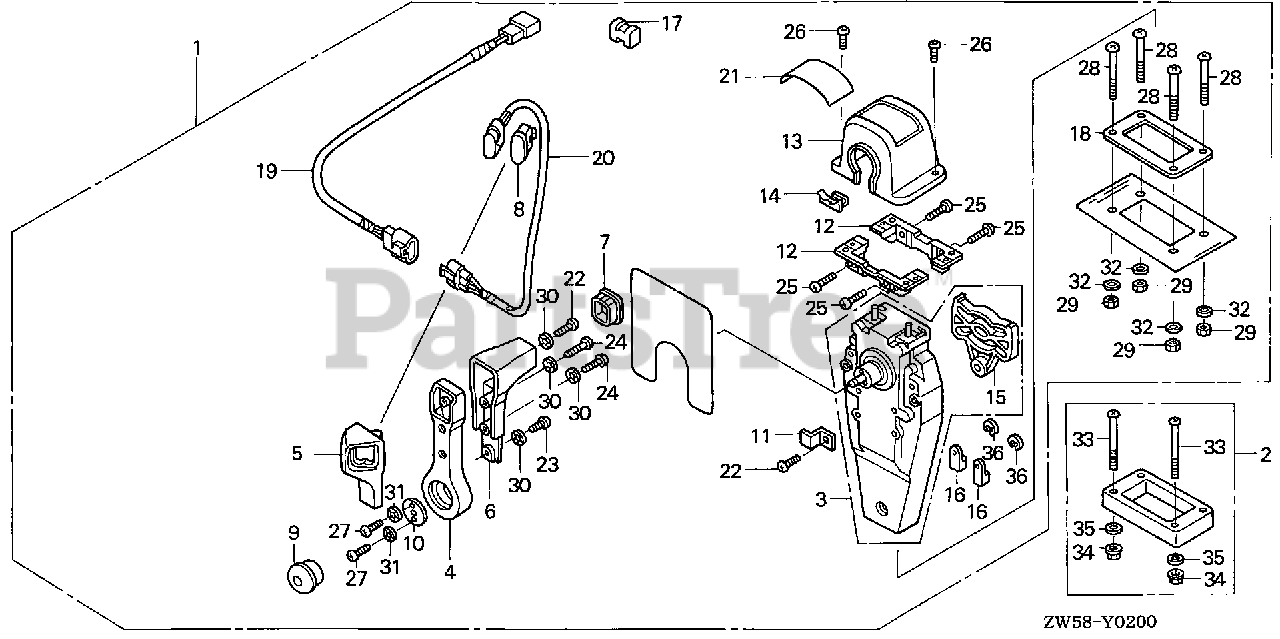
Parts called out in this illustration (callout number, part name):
1	BOX KIT, REMOTE CONTROL (TOP MOUNT SINGLE)(R)
2	SPACER KIT, REMOTE CONTROL BOX (TOP MOUNT SINGLE)
3	HOUSING ASSY., L. (INNER) (TOP MOUNT)
4	HANDLE, REMOTE CONTROL
5	COVER, L. GRIP
6	GRIP, REMOTE CONTROL HANDLE
7	CAP, GRIP
8	CAP, SWITCH
9	BUTTON, THROTTLE
10	PLATE, HANDLE
11	PLATE, CABLE CLAMP
12	BRACKET, REMOTE CONTROL HOUSING
13	HOUSING, REMOTE CONTROL BOX
14	HOUSING, LEAD
15	PLATE, DWELL
16	TERMINAL, CABLE
17	SPACER, CABLE CLAMP
18	GASKET, SINGLE
19	SUB-HARNESS ASSY., POWER TRIM-TILT (A)
20	SWITCH ASSY., POWER TRIM-TILT (A)
21	MARK, REMOTE CONTROL (SINGLE)
22	SCREW, PAN (5X16)
23	SCREW, PAN (5X10)
24	SCREW, PAN (5X20)
25	SCREW, PAN (5X18)
26	SCREW, PAN (4X10)
27	SCREW, PAN (6X18)
28	SCREW, PAN (5X40)
29	NUT, HEX. (5MM)
30	WASHER, LOCK (5MM)
31	WASHER, LOCK (6MM)
32	WASHER, PLAIN (5MM)
33	SCREW, PAN (5X65)
34	NUT, HEX. (5MM)
35	WASHER, PLAIN (5MM)
36	E-RING (6MM)
